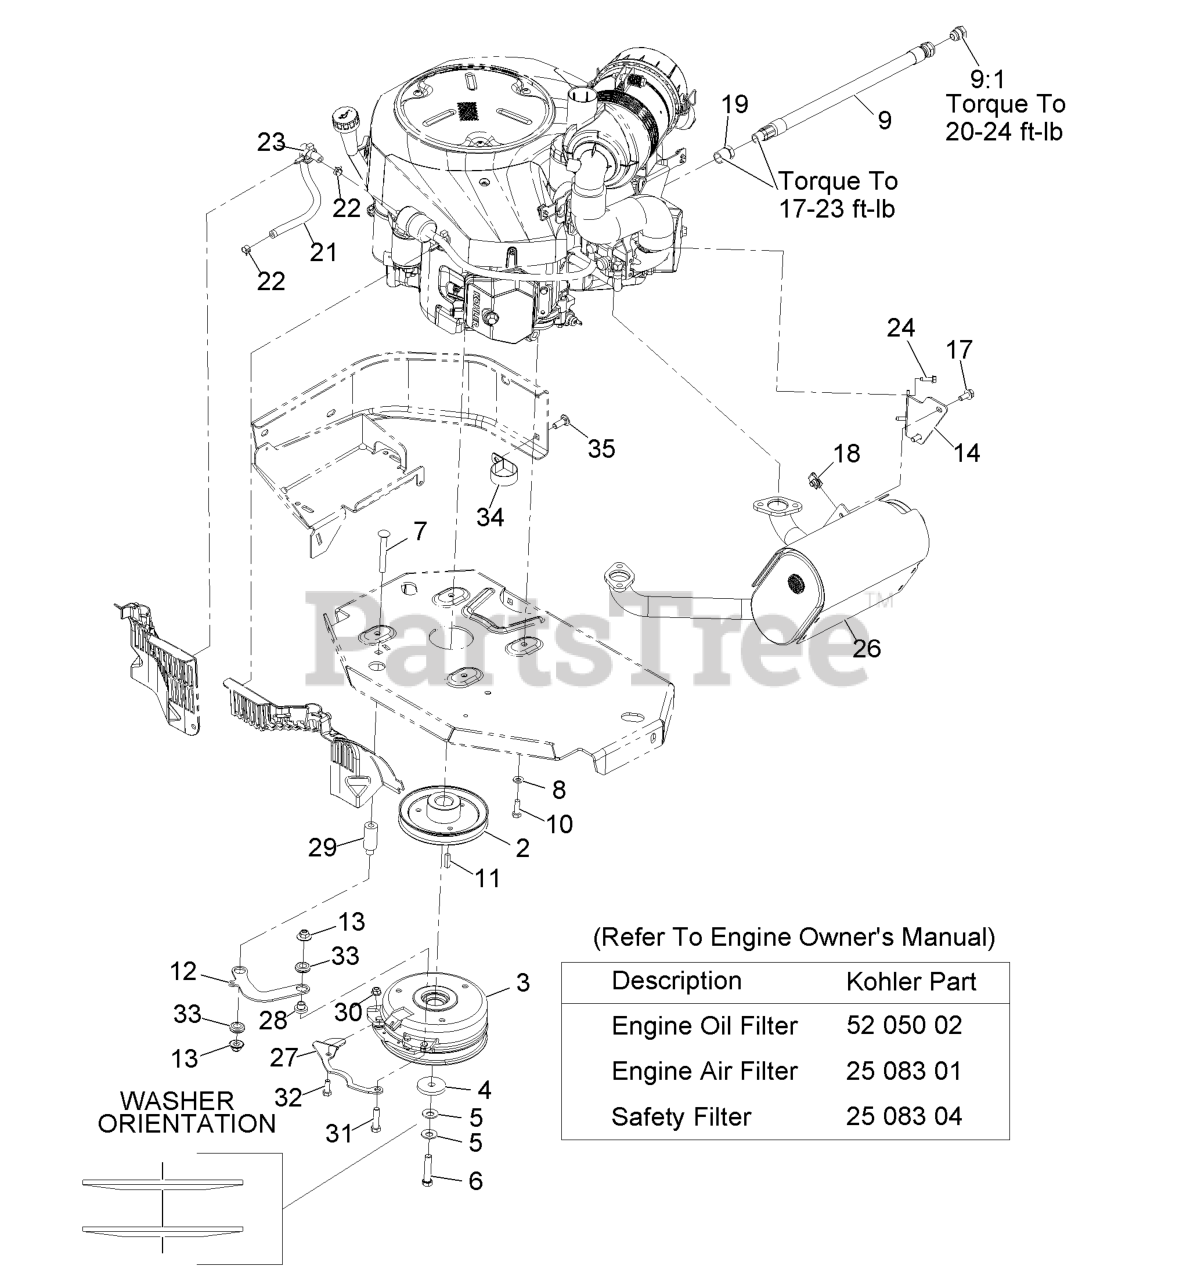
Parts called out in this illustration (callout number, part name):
2	SHEAVE
4	WASHER-CLUTCH
5	WASHER-SPRING
6	SCREW-HH W/LOCTITE
7	SCREW-CARR
8	WASHER-SPRING
10	SCREW-HH
12	LINK-ANCHOR, CLUTCH
13	Nut-Nyloc 3/8-16 Flg
17	SCREW-HHF
19	BUSHING
22	CLAMP-HOSE
23	CLAMP-HOSE
26	MUFFLER
27	BELT-GUIDE
30	NUT-HF, NI
31	SCREW-HH
32	SCREW-HH
33	GROMMET-RUBBER
34	CLAMP-R
35	SCREW-CARR
